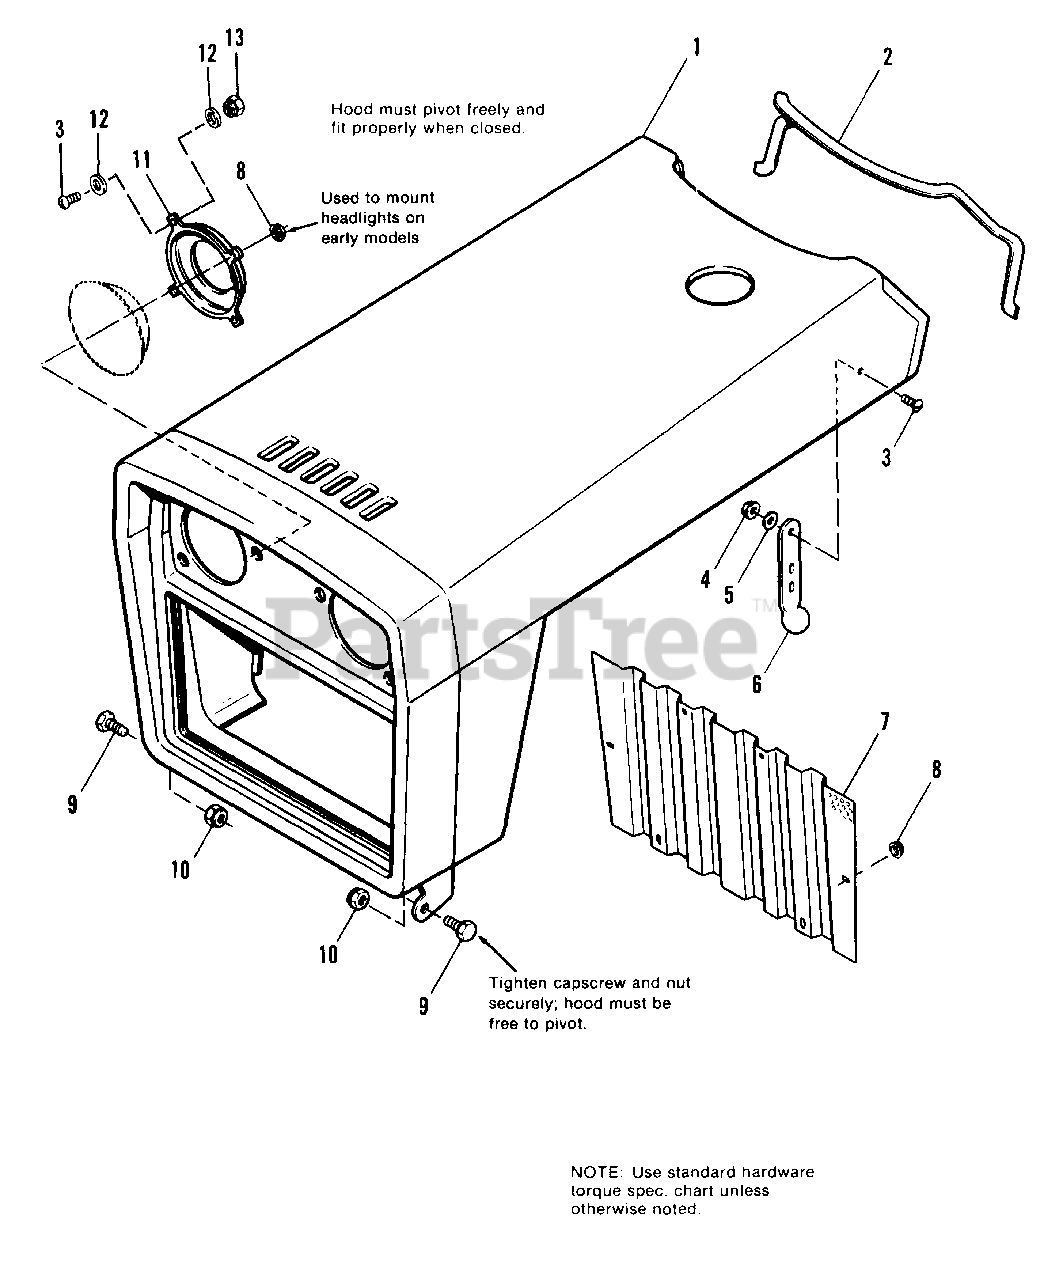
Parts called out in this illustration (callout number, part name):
1	* HOOD & GRILLE ASSY.
2	MOULDING, Hood
3	SCREW, Truss Hd., #10-32 x 1/2 (Qty. 2 used on early models)
4	LOCKNUT, Hex, #10-32
5	WASHER, Special
6	STRAP, Hood
8	LOCKNUT, Pal
9	CAPSCREW, Hex Hd., 3/8-16 x 1
10	LOCKNUT, Hex, 3/8-16
11	BRACKET, Headlight
12	WASHER, Flat, 3/16
13	NUT & WASHER, #10-32
